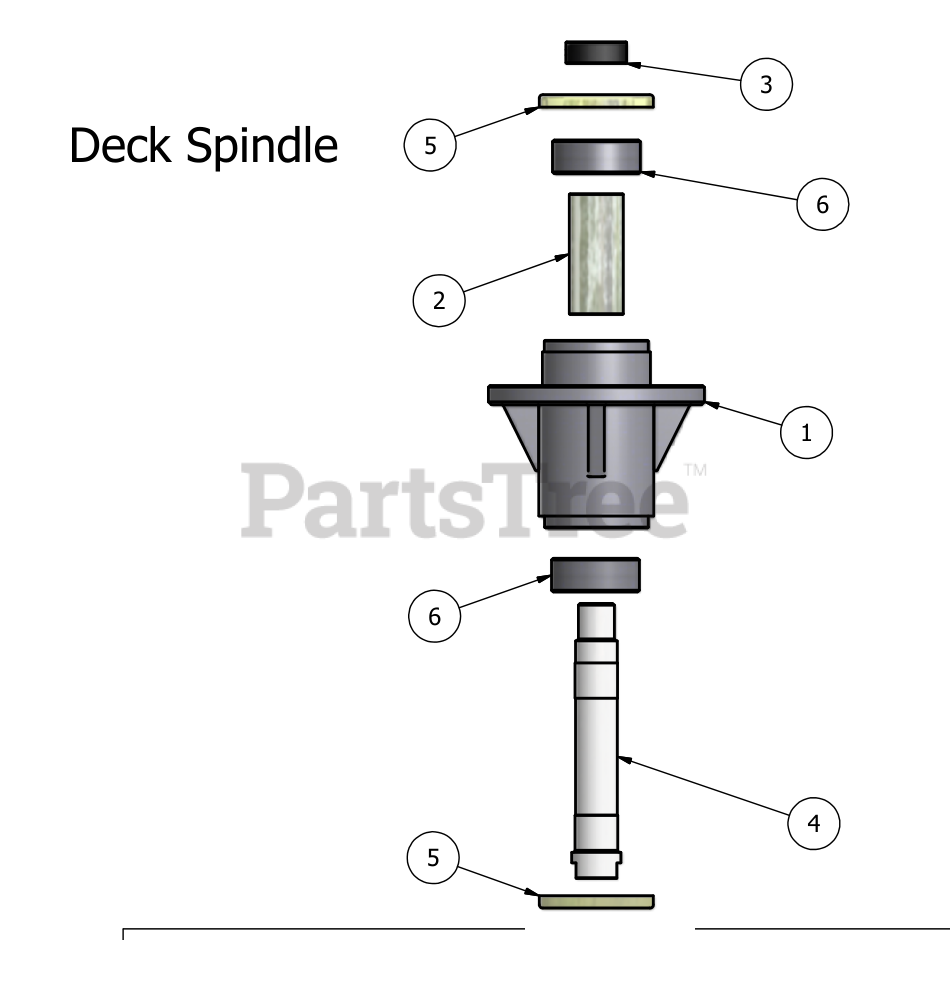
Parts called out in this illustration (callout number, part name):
1	Spindle Housing
2	Spindle Spacer
3	Spindle Coller
4	Spindle Shaft
5	Bearing Cover
